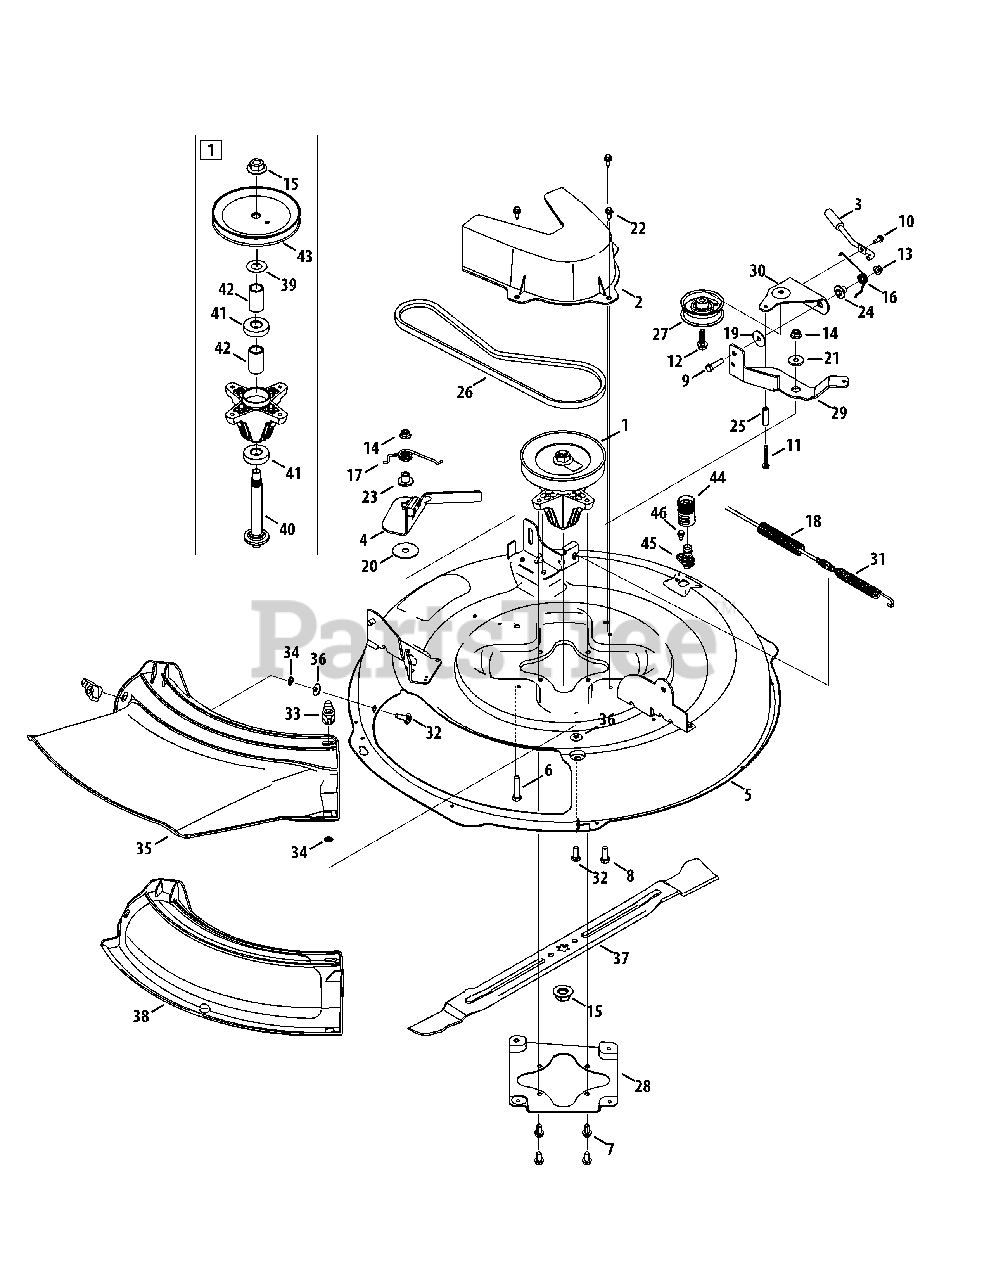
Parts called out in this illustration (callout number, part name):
1	Spindle Pulley Assembly, 6.3 DIA
2	Deck Belt Cover
3	Idler Rod Assembly
4	PTO Brake Assembly Bracket
5	Deck, 30" w/ Nozzle
6	Hex Cap Screw, 3/8-16 x 1.75
7	Tap Screw, 5/16-18, .750
8	Hex Head Screw, 3/8-16, 1.00
9	Hex Cap Screw, 5/16-18 x 1.25
10	Tap Scew, 1/4-20, 0.500
11	Tap Screw, 1/4-20, 1.750
12	Tap Screw, 3/8-16, 1.250
13	Flange Lock Nut, 5/16-18
14	Flange Lock Nut, 3/8-16
15	Flange Nut, 5/8-18
16	PTO Torsion Spring
17	Brake Torsion Spring
18	Compression Spring, .625 x 4.0
19	Flat Washer, .330x1.250x.060
20	Flat Washer, .406 x 1.920 x .060
21	Shoulder Spacer, .625 ID X .169
22	Shoulder Screw, .368 X.113: 1/4-20
23	Shoulder Spacer, .173 x .625 x .563
24	Shoulder Spacer, .134 x .500 x .438
25	Spacer, .260 X .372 X 1.420 LG
26	V-Type Belt, 43.5 LG
27	Flat Idler Pulley, 2.75 OD
29	Lower Floating Idler Bracket
30	Upper Floating Idler Bracket
32	Carriage Screw, 5/16-18, 1.00
33	Wing Knob, 5/16-18
34	Speed Nut, .3125 ID
35	Chute Deflector
36	Bevel Washer, .340X.872X.060
37	Cutting Blade, 30.00" 3-IN-1
38	Mulch Plug
39	Shim Washer, .760X1.500X.030
40	Spindle Shaft, 6.11 LG.
41	Ball Bearing, .787ID X 1.85 ODX.551
42	Spacer, .792 X 1.060 X 1.860 LG
43	Deck Pulley, 6.3 DIA
44	Water Nozzle Adapter
45	Deck Wash Nozzle
46	Shoulder Screw, 1/4-20 x 0.500
